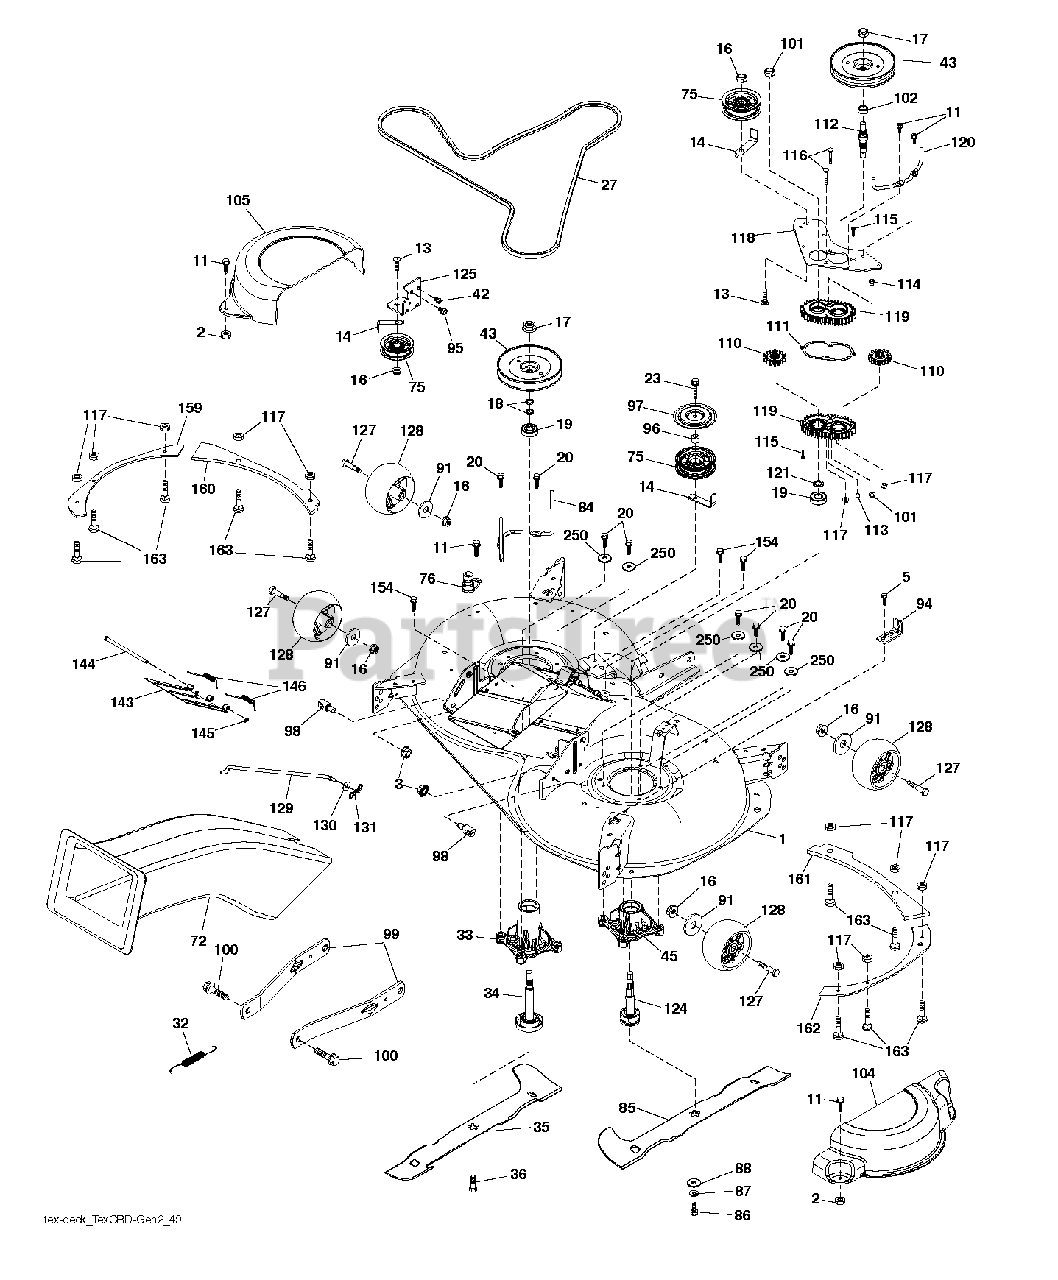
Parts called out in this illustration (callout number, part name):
1	DECK SVC 107HP.EZMUL.498
2	PALNUT 1/4
3	NUT LOCK HEX FLANGE 5/16-18
5	BOLT.5/16HEX.WHS.HD
11	SCREW.1/4-20X5/8
13	BOLT.3/8-16X1.50
14	KEEPER, BELT IDLER
16	NUT LOCK FLG 3/8-16 UNC
17	NUT.FLANGE.LOCK.TOP
18	WASHER.SPACER.MANDREL
20	SCREW, WASHER HEAD
23	SCREW LT
27	BELT BELT. ELECTRIC MOWER DRIV
32	SPRING 107CM & 97CM ELECTRIC D
33	HOUSING.MANDREL.REV.TALL.N/GRS
34	SHAFT ASM.REV.TALL.N/GREASEBL
35	BLADE.107.LH.SINGLE.NON.QD
36	BOLT.WASHER.ASM.7/16-2
42	SCREW
43	PULLEY PULLEY MANDREL 5.438 PD
45	RP HOUSING.MANDREL.REV.REVS.
72	RB CHUTE 107/97 TEX GENII
75	FLAT IDLER PULLEY
76	PORT.WASHOUT
84	KEEPER KEEPER. LH MANDREL BELT
85	BLADE.107.RH.SINGLE.NON.QD
87	LOCKWASHER
88	WASHER.BLADE
91	WASHER
94	BRKT.CLUTCH.CABLE
95	SCREW, 3/8-16X3/4
96	SPACER
97	PROTECTOR
98	STUD.FASTNER.W/ANTI-ROTATE
99	ARM.SUSPENSION.MOWER.R
100	BOLT.SHOULDER
101	NUT.CROWNLOCK.9/16 -18.UNC
102	SPACER BEARING
104	COVER.MANDREL.107.RH.GEN.2
105	COVER.MANDREL.107.LH.GEN.2
110	GEAR GEAR OUTPUT
111	GASKET GASKET GEARCASE
112	SHAFT SHAFT. CRD GEARCASE ADAP
113	PLUG PLUG OIL
114	VALVE VALVE RELIEF
115	SCREW
116	BOLT.CARIGE.SS.1/4-20X1.75GR5
117	NUT T
118	ARM ARM. CLUTCHING 107 TEX CRD
119	GEARCASE GEARCASE SUBASM
120	KEEPER KEEPER. RH MANDREL BELT
121	WASHER WASHER
124	SUB.ASM.REVERSE.THREAD.REV
125	BRACKET
127	BOLT.SHOULDER.3/8-16X3-5/8.
128	WHEEL. GUAGE RALLY
129	ROD ROD. SWAY CRD GEN II
130	WASHER
131	PIN.COTTER.5/16.BOW TI
143	COVER DOOR.107 CM CRD EZ MULCH
144	PIN PIN.HINGE
145	E-RING.5/16"
146	SPRING SPRING: EZ MULCH DOOR
154	SCREW T-30 1/4-20 X
159	PLATE.107CRD.LH.SIDE.BLTON
160	PLATE.107CRD.LH.FRONT.BOLT-ON
161	PLATE.107CRD.RH.FRONT.BOLT-ON
162	PLATE.107CRD.RH.SIDE.BOLT-ON
163	BOLT
